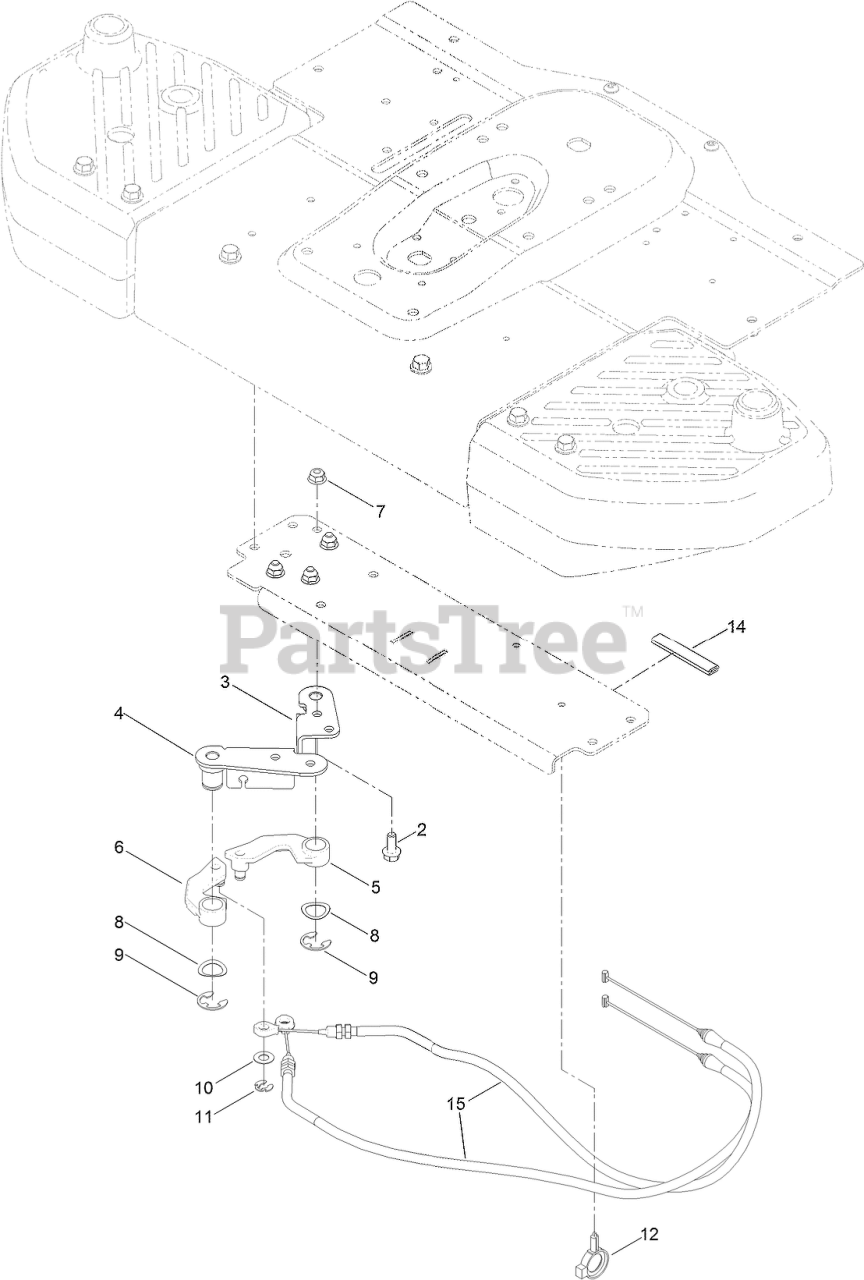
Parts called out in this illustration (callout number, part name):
2	SCREW-HHF
3	CABLE BRACKET ASM
4	CABLE BRACKET ASM
5	ARM-CABLE, RH
6	ARM-CABLE, LH
7	NUT-HF, NI
8	WASHER-BOWED
9	E-RING
10	WASHER-THRUST
11	RING-RETAINING
12	CLAMP-HOSE
14	STRIP-SEAL
15	CABLE-STEERING
